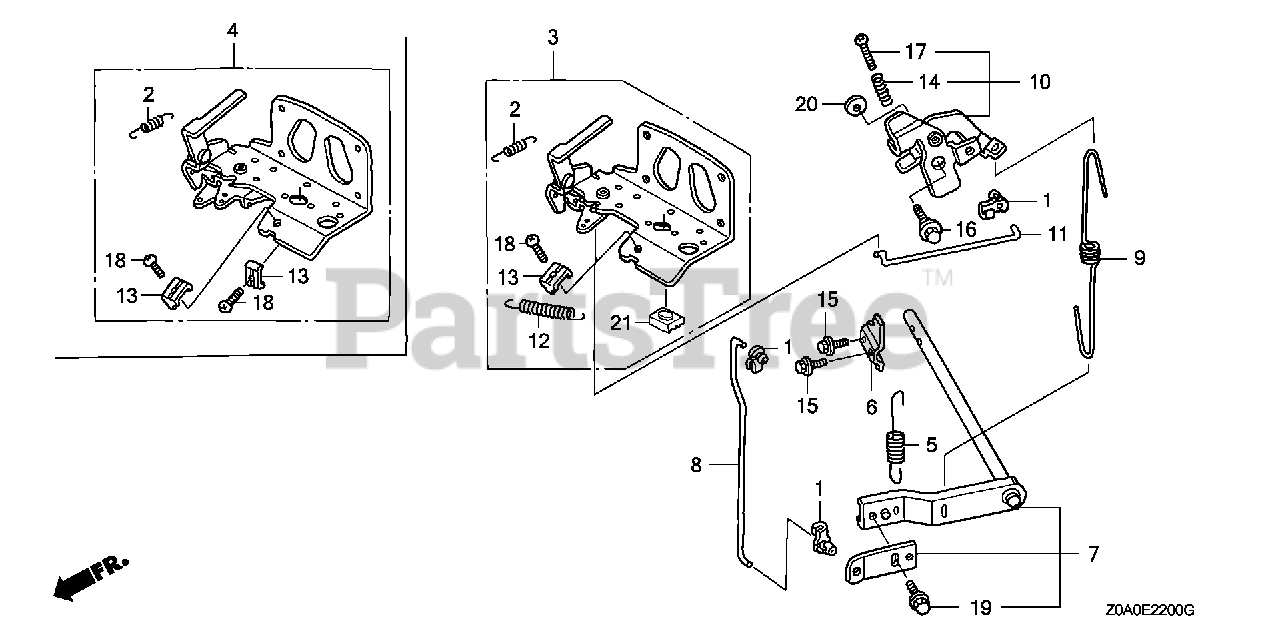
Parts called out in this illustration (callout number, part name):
1	ROD, JOINT
2	SPRING, CHOKE RETURN
4	CONTROL ASSY. (2-LEVER)
5	SPRING, STARTER
6	FORK, GOVERNOR
7	ARM, GOVERNOR
8	ROD, GOVERNOR
9	SPRING, GOVERNOR
10	LINK, GOVERNOR
11	ROD, GOVERNOR LINK
13	HOLDER, CABLE
14	SPRING, CONTROL ADJUSTING Use from Engine SN 2327377.
15	BOLT, FLANGE (5X10) Use from Engine SN 2327377.
16	BOLT, FLANGE (6MM) (CT200)
17	SCREW, RECESSED (5X25)
18	SCREW, PAN (5X16)
19	BOLT, FLANGE (6X10)
20	WASHER, PLAIN (6MM)
